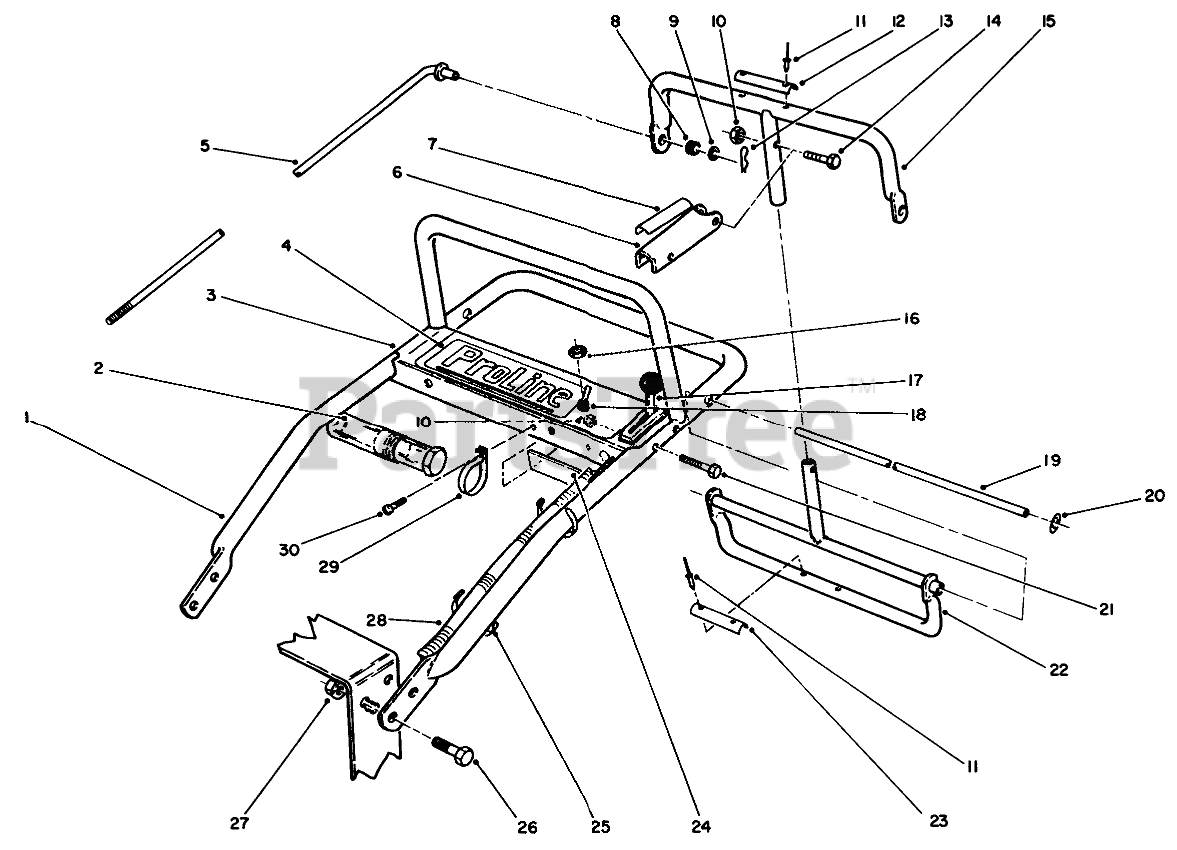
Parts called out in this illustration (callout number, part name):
1	Handle-Upper
2	TUBE-MANUAL
3	CONTROL PANEL B
4	DECAL - PANEL
5	CONTROL ROD
6	Lever-Parking Brake
7	DECAL-LEVER, PARKING
8	GROMMET-RUBBER
9	WASHER-FLAT
10	NUT-LOCK, NI
11	RIVET-BLIND
12	DECAL-CONTROL BAR
13	PIN-COTTER
14	SCREW-SHH
15	Bar-Control
16	NUT
17	CONTROL-THROTTLE
18	Switch
19	PIVOT ROD
20	NUT-PUSH-ON, CIRCULAR
21	SCREW-SHH
22	Control Pivot
23	DECAL-REVERSE HANDLE
24	PANEL-BOTTOM
25	TIE-CABLE
26	SCREW-HHF
27	NUT-HF
28	WIRE HARNESS
29	CLAMP-R
30	SCREW-HWHTF
